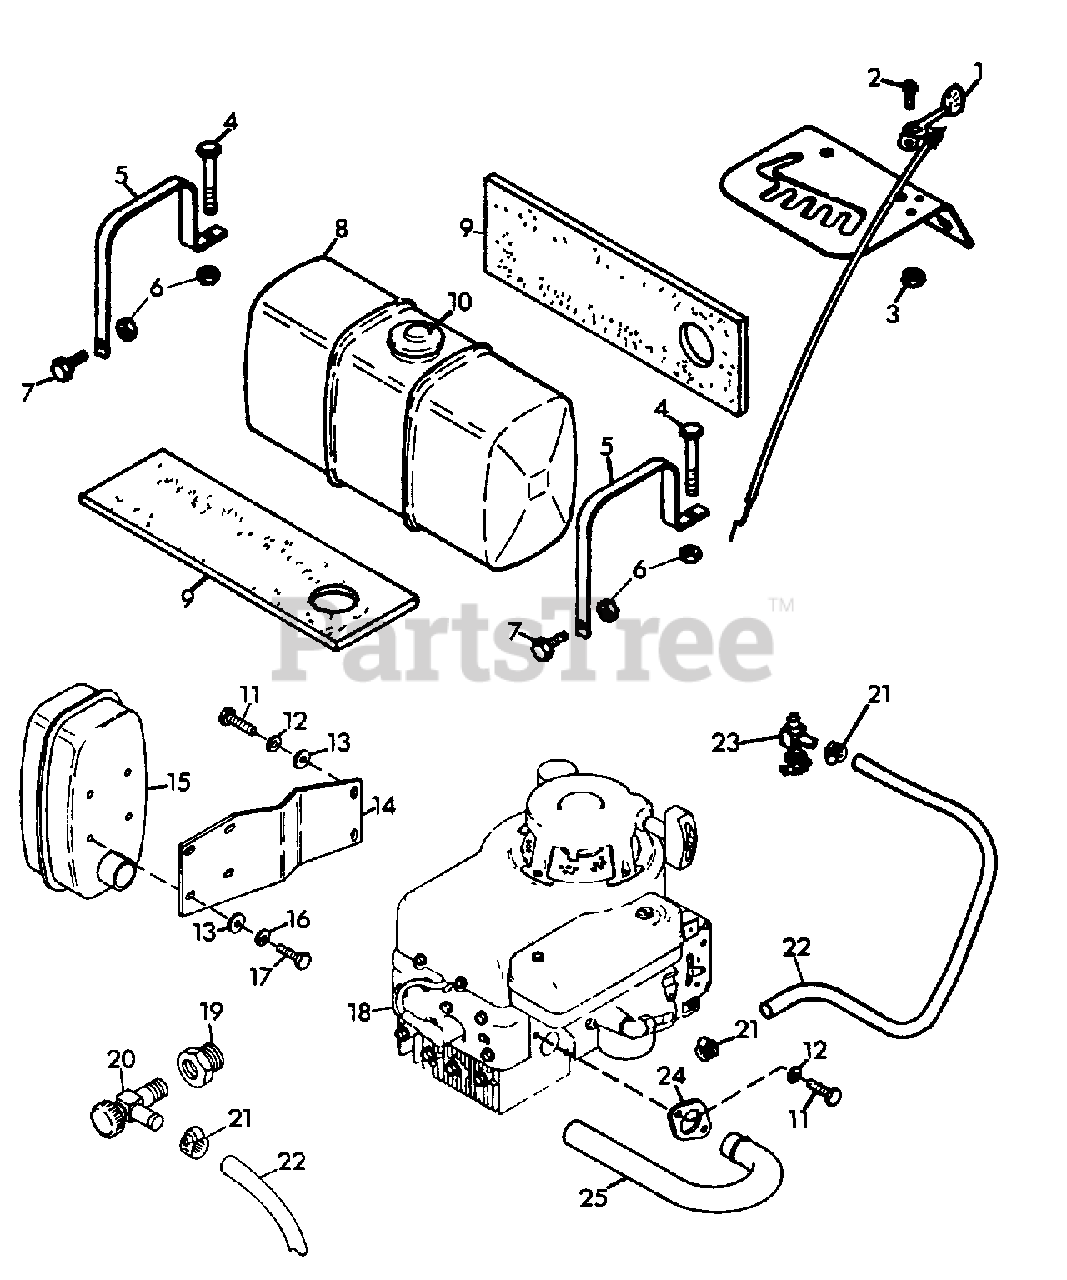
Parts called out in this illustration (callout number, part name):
1	LEVER, CONTROL
2	SCREW, MACH. 10-24X.50 PHD
3	NUT, LOCK 10-24
4	BOLT, HEX 1/4-20X1.75
5	STRAP, FUEL TANK
6	NUT, LOCK 1/4-20
7	BOLT, HEX 1/4-20X.625
8	TANK, FUEL (12 QTS.)
9	PAD, GAS TANK
10	CAP, GAS TANK
18	ENGINE, 12 H.P. B&S
18	ENGINE, 12.5 H.P. KAWASAKI
19	ADAPTOR, OIL DRAIN
20	COCK, OIL DRAIN
21	CLAMP, HOSE
22	HOSE, FUEL
23	VALVE AND STRAINER
NS	KIT, OIL FILTER
